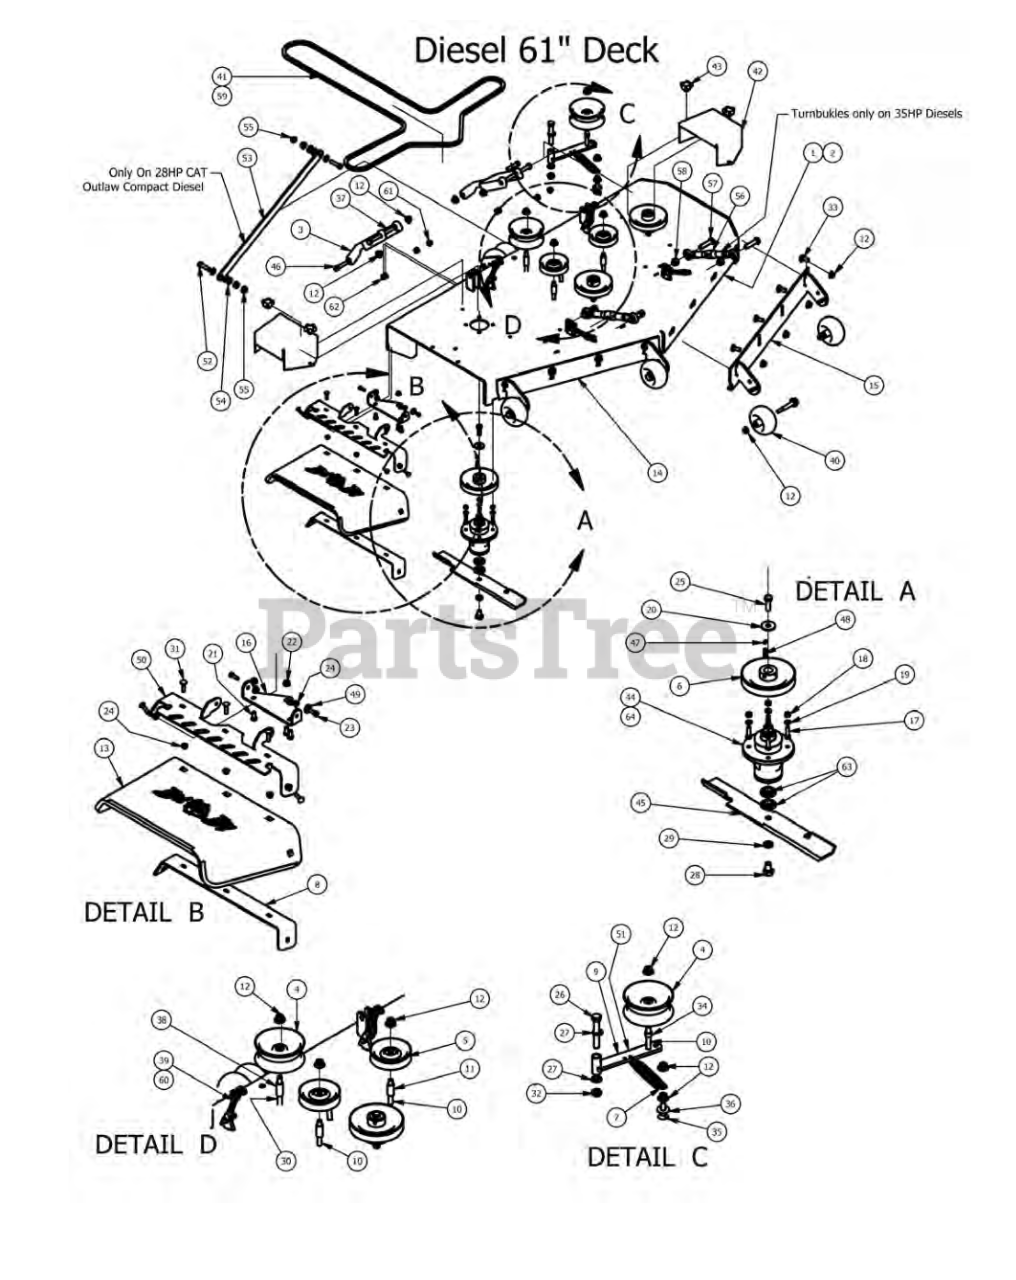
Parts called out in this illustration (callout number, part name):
1	61" Outlaw Deck Only 28HP Diesel
2	61" AOS Deck Only 2012 35Hp Diesel
3	Deck Arm Assembly
4	5 3/4 Flat Idler-32F1-92-008 Pulley
5	4 3/4" Idler Pulley
6	6.1/4" Drive Pulley
7	2009 Deck/Pump Idler Spring
8	60" Lower Hanger
9	Deck Idler
10	1/2 x 3 1/2 Flange Bolt Grade 8
11	Pup Pulley Spacer
12	1/2-13 Nylon Insert Flange Nut
13	Rubber Discharge Chute
14	61 Outlaw Adjustable Deck Front (Left)
15	61 Outlaw Adjustable Deck Front (Right)
16	Discharge Chute Hanger (deck mounted)
17	3/8" x 1 1/4" Hex Bolt
18	3/8-16 Hex Nuts Zinc
19	3/8 Lockwasher Zinc
20	1/2 Belleville Washer
21	3/8" x 3/4" Hex Bolt
22	3/8" Flange Nut
23	5/16" x 1" Bolt
24	5/16" Flange Nut Zinc W/Serrations
25	1/2"-20 x 1 1/2-Grade 5 Fine Thread Bolt
26	5/8" x 4" Hex Bolt
27	635 ID Plastic Washer
28	5/8" x 1 1/2" Grade 8 Bolt
29	5/8" Lock Washer
30	1/2" x 4" Bolt (Grade 8)
31	5/16" x 1 1/4" Camage Bolt
32	5/8" Nylock (1/2 Jam)
33	1/2" x 1 1/4 Carriage Bolt
34	Spacer 3/4 OD X 1/2 ID X.75
35	1/2 x 2" Carriage Boit
36	1/2" Flat Washer
37	1/2" x 5 1/2" Bolt
38	1 3/4" Pulley Spacer
39	4-Link Adjustable Deck Hange 35HP Diesel
40	Deck Wheel
41	B226 Belt For 2012 Outlaw 28Hp Diesel
42	Pulley Cover
43	5/16" Knob
44	Double Bearing Spindle Only on 28hp Diesel
45	61 inch Fusion Blade
46	1/2-13X 2-1/4 GR Hex Bolts
47	5/16 Set Screw
48	1/4" x 1" Key
49	360 ID Plastic Washer
50	60" Upper Hanger Plate
51	Deck Idler Assembly-parts of Assembly 12,4,34,10,9
52	1/2-13x2 GR 5 Hex Bolt
53	Outlaw Panhard Link
54	505 Nylon Spacer
55	1/2" Flange Nut
56	Tumbuckle (Top Link)
57	5/8" x 2 1/2" Hex Bolt
58	5/8 Std NC Nylock Nut
59	B236 Belt Diesel EZ Ride 35Hp Diesel only
60	3 Link Adjustable Deck Hanger only on 28HP Diesel
61	Flange Bushing For Deck Arm upper
62	Flange for Lower Deck Arm
63	Double Bearing For Spindle
64	Doublé Bearing Spindle Only on 35hp Diesel
